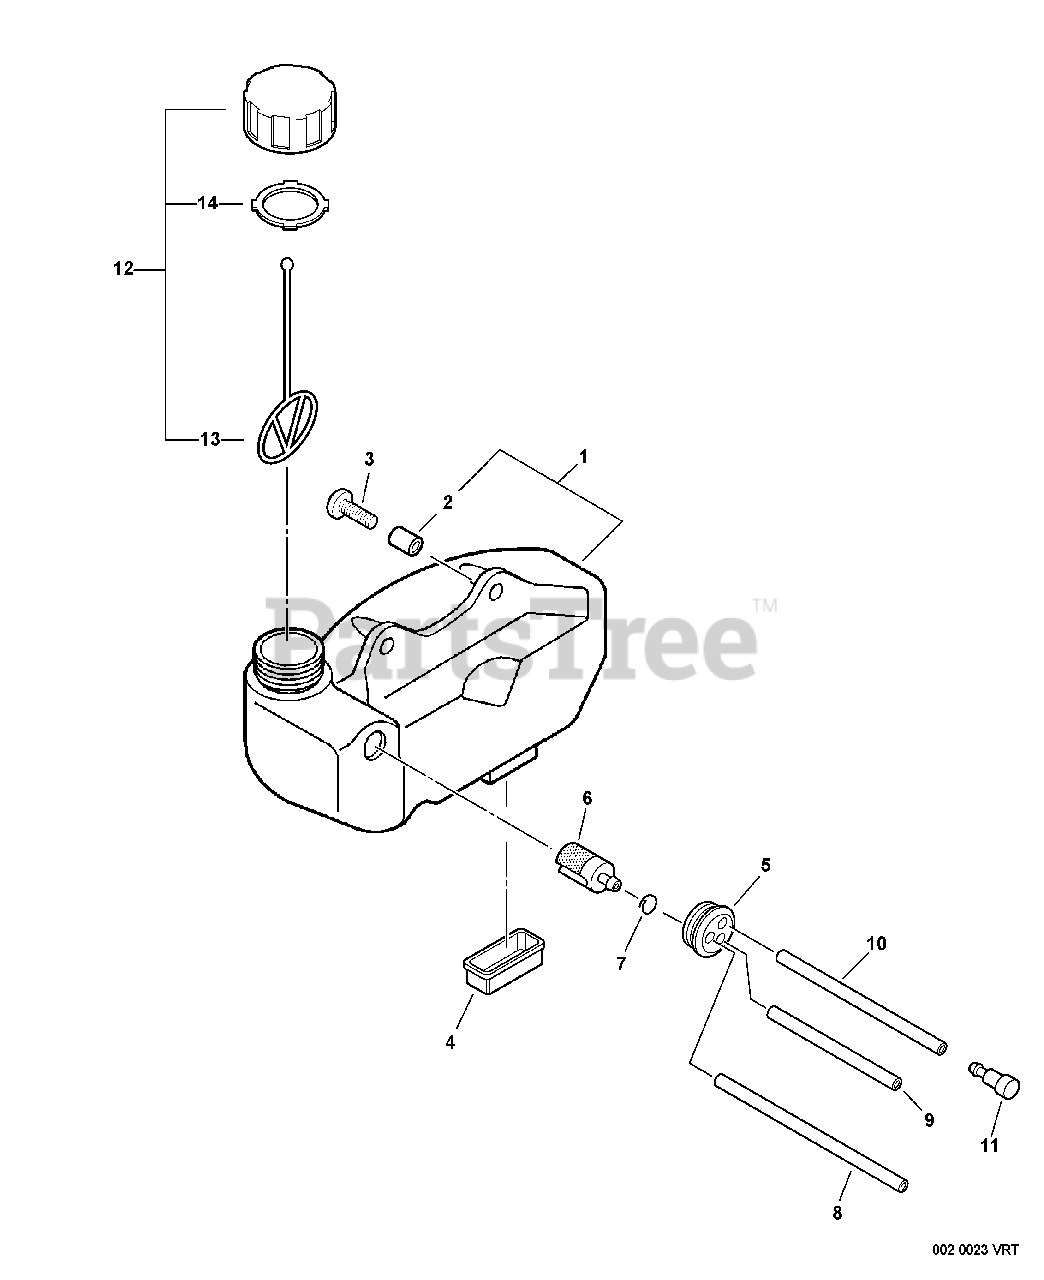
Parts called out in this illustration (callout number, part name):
1	FUEL TANK ASSY
3	SCREW - 5X15
4	CUSHION, FUEL TANK
5	GROMMET
6	FILTER, FUEL
7	CLIP - 6
8	PIPE - 3X5X195 -- BLACK
9	PIPE - 3X6X110 -- CLEAR
10	PIPE - 3X5X70 -- BLACK
11	VENT, FUEL TANK
12	CAP ASSY - ORANGE
13	CONNECTOR, CAP
14	GASKET, CAP
15	RePower TUNE-UP KIT
16	RePower TUNE-UP KIT
17	RePower FUEL SYSTEM KIT
